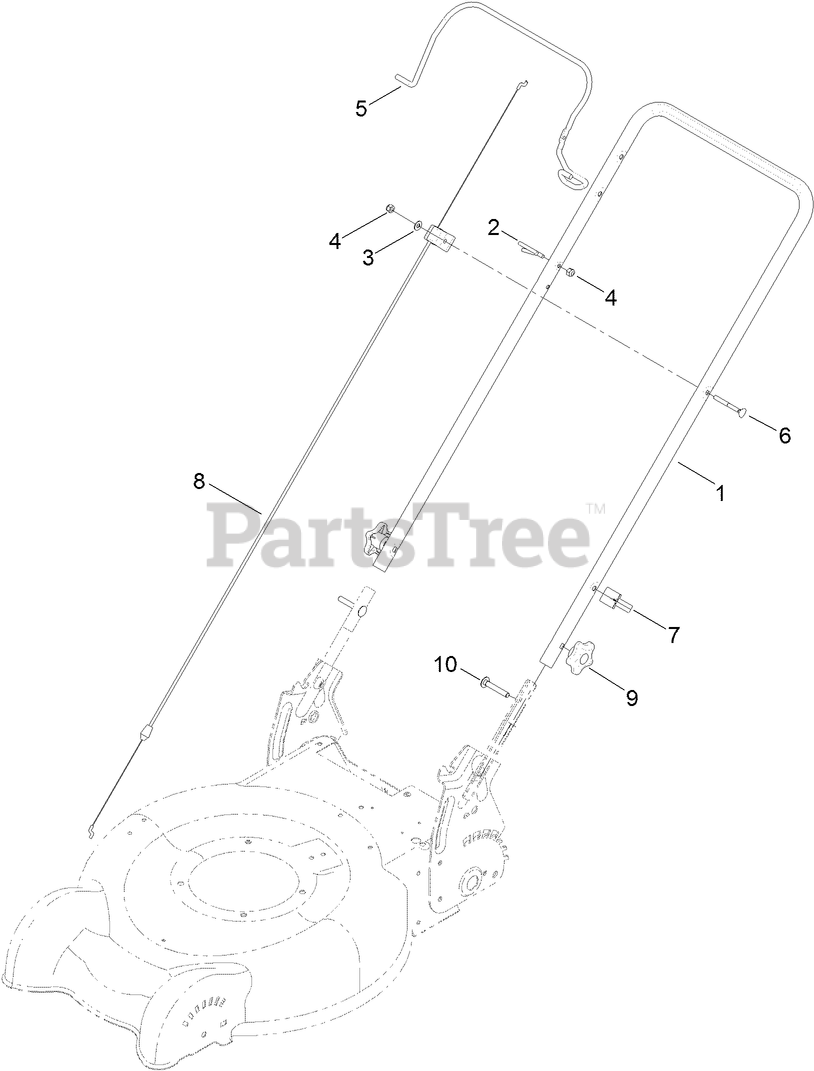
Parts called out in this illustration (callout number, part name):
1	HANDLE-UPPER
2	GUIDE-ROPE
3	WASHER-FLAT
4	NUT-LOCK, NI
6	SCREW-HANDLE
7	GUIDE-CABLE
8	CABLE-BRAKE, ENGINE
9	KNOB-HANDLE
10	BOLT-CARR
